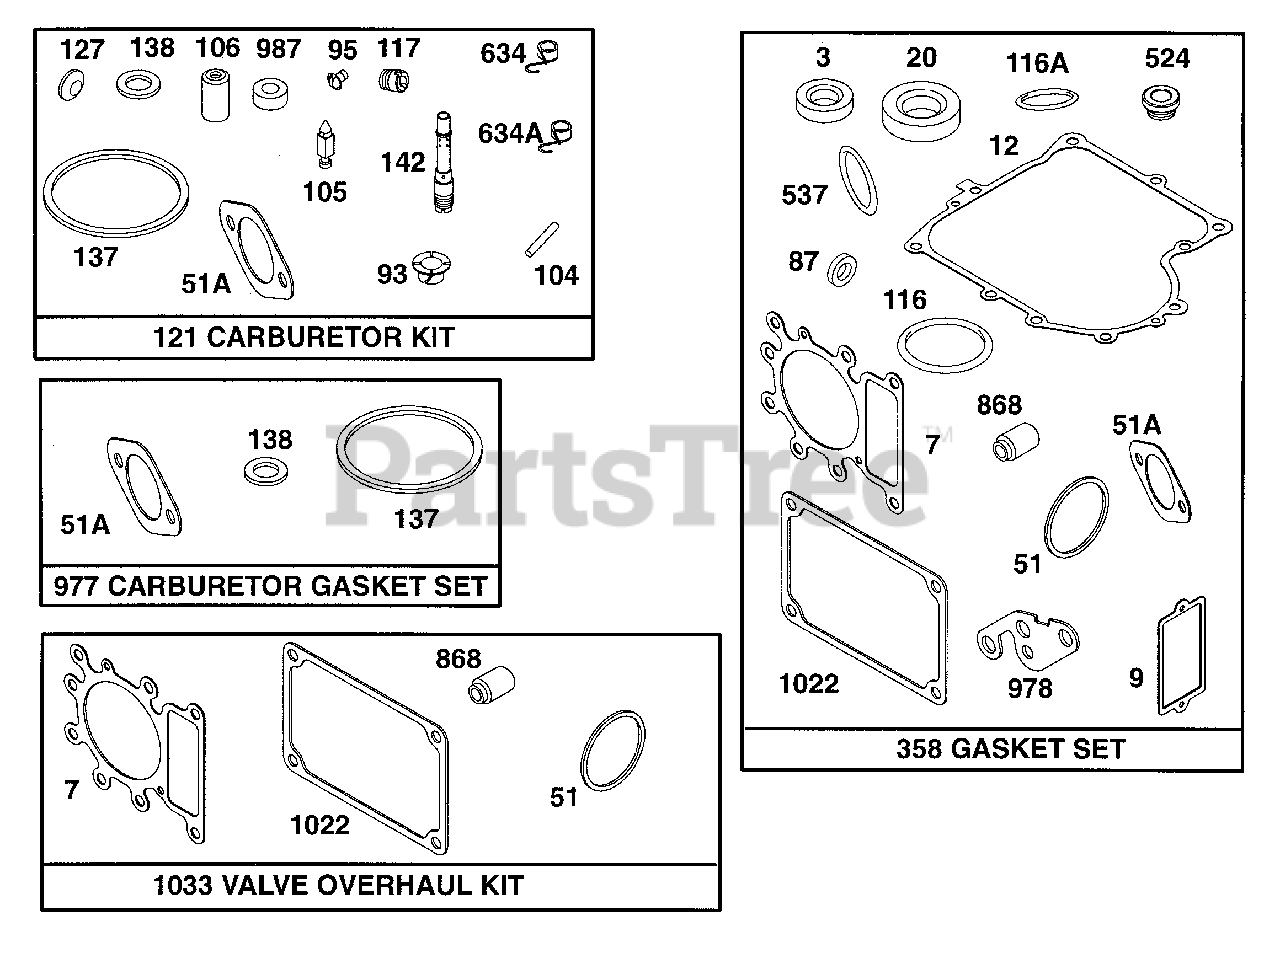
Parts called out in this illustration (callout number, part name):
3	Oil Seal
7	Cylinder Head Gasket
9	Breather Gasket
12	Crankcase Gasket
20	Oil Seal
51	Seal-O-Ring
51A	Intake Gasket
87	Governor Shaft Seal
93	Throttle Shaft Bushing
95	Choke Throttle Screw
104	Float Hinge Pin
105	Valve Float Needle
106	Inlet Seat
116	Seal-O-Ring
116A	Seal-O-Ring
117	Main Jet
121	Carburetor Jet
127	Welch Plug
137	Float Bowl Gasket
138	Seal Washer
142	Carburetor Nozzle
358	Gasket Set
524	Fill Tube Seal
537	Air Cleaner Gasket
634	Spring Assembly Seal
634A	Spring Assembly Seal
868	Valve Seal
977	Carburetor Gasket Set
978	Oil Adapter Gasket
987	Throttle Shaft Seal
1022	Rocker Cover Gasket
1033	Valve Overhaul Kit
